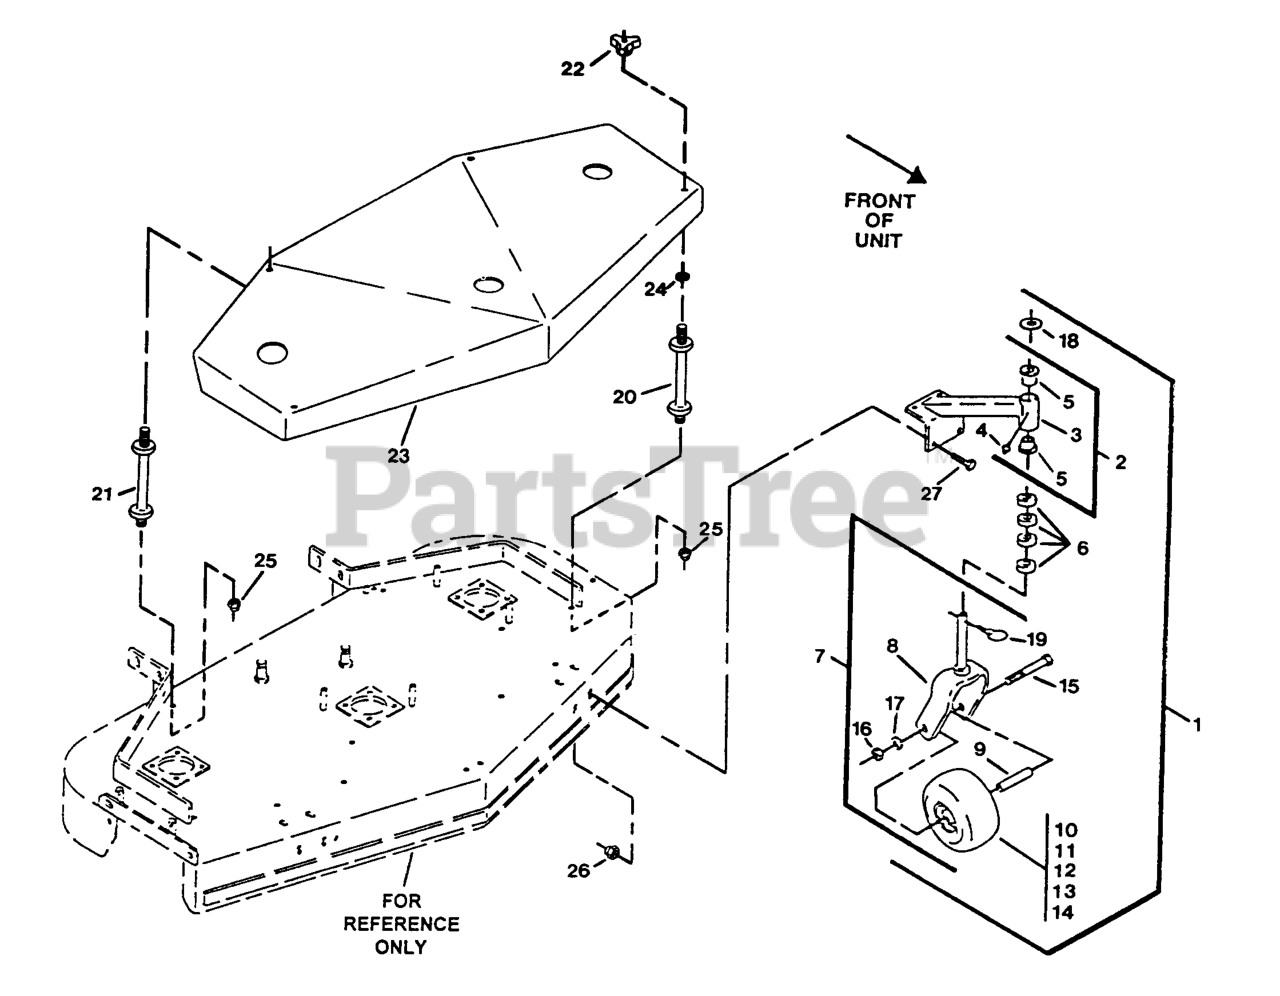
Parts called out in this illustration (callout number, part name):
1	CASTER/MOUNT ASM
2	SUPPORT ASM
5	BEARING-FLANGED
6	SPACER-CASTER
13	BEARING
14	BUSHING
18	WASHER-FLAT
20	STUD-SHIELD, BELT (SHORT)
21	STUD-SHIELD, BELT (LONG)
22	KNOB-3 PRONG
23	ASM,SHIELD BELT 48
